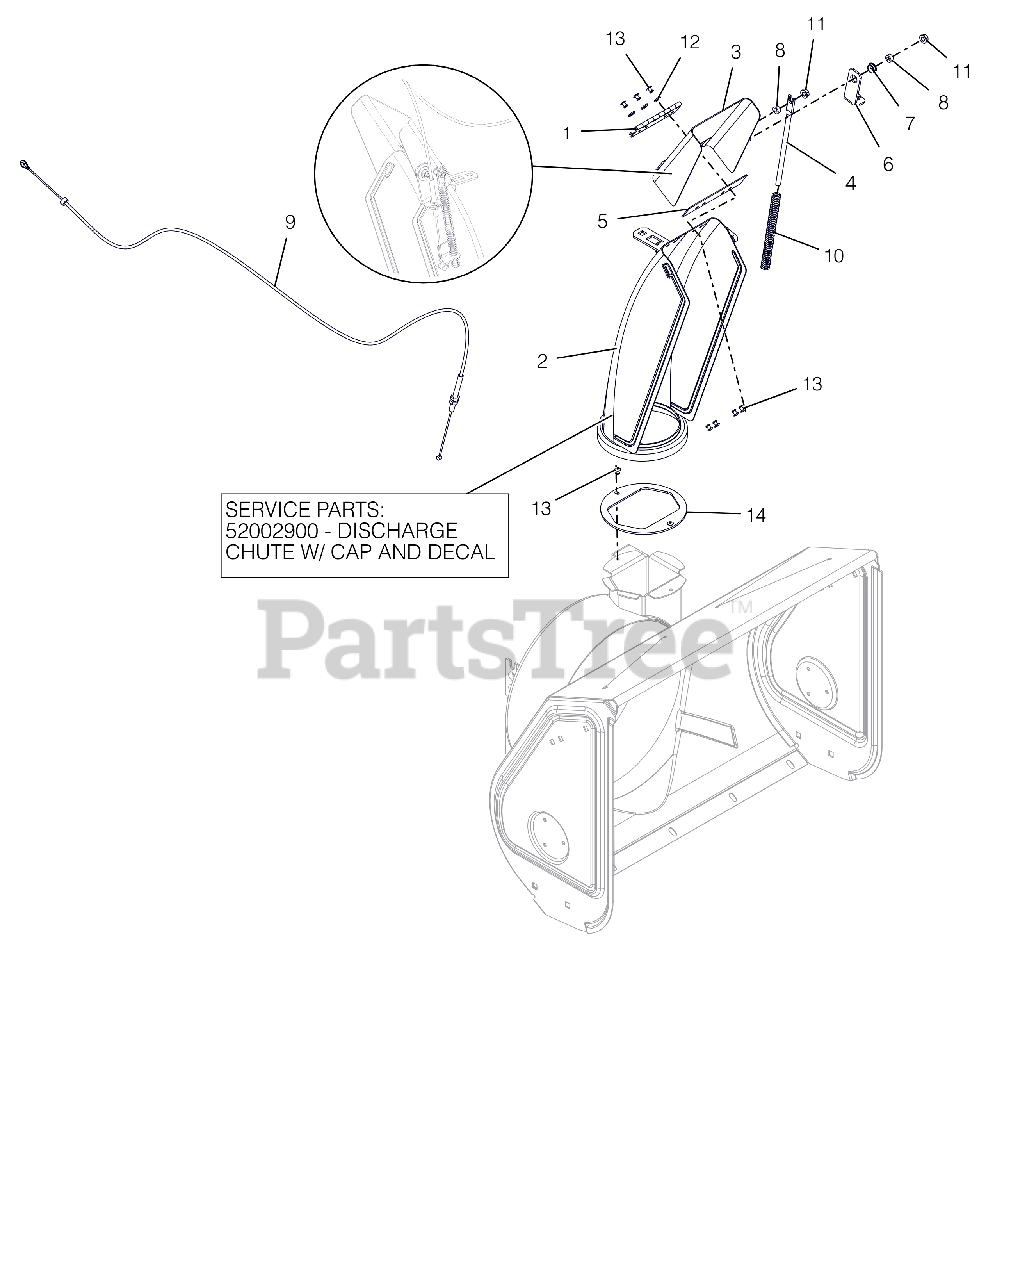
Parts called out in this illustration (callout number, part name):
2	CHUTE, COMPACT-TALL W/REMOTE
2	CHUTE, DISCHARGE W/REM.CAP,DEC
3	CAP,REMOTE - COMPACT (W/DECAL)
4	ROD, DEFLECTOR CAP
5	CAP SEAL 5.25
6	BRACKET, CABLE ANCHOR
7	BUSHING, POLYLINER-.50 SNAPIN
8	BSHG-SLV .265X.500X.219
9	CABLE, DEFLECTOR - COMPACT
10	SG-COMP .08X.40X6.50 14#/IN
11	@NUT-LK-TOP-FLG .25-20 YWZC
12	WSHR-FL-STL .196X.500X.06 YZ
13	RVT-POP .187 YZ
14	BAFFLE, COMPACT DISCHARGE
